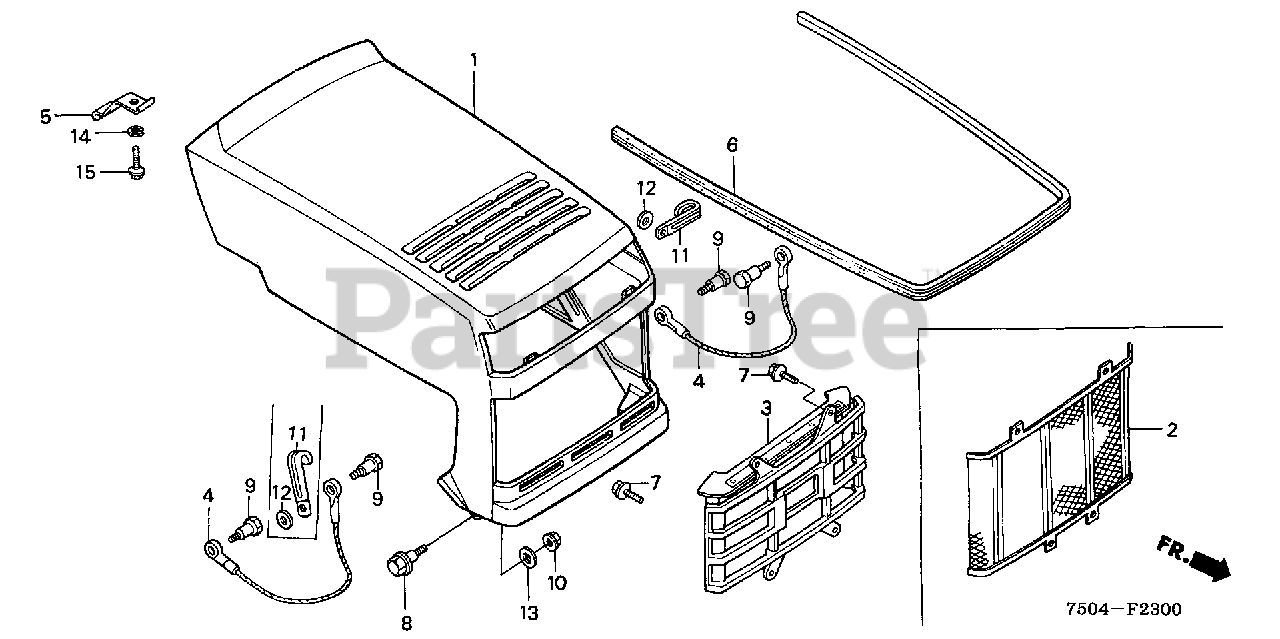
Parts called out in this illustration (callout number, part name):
1	HOOD ASSY. *R136* (DIANA RED)
2	EXPAND, FR.
4	STOPPER, HOOD
5	SPRING, LOCK
6	MOLDING, HOOD
7	BOLT, FLANGE (6X8)
8	BOLT, HINGE
9	BOLT, HANDLEBAR
10	NUT, SELF-LOCK (8MM)
11	CLIP, WIRE HARNESS
12	WASHER, PLAIN (6MM)
13	WASHER, PLAIN (8MM)
14	WASHER, SPRING (6MM)
15	BOLT, FLANGE (6X12)
